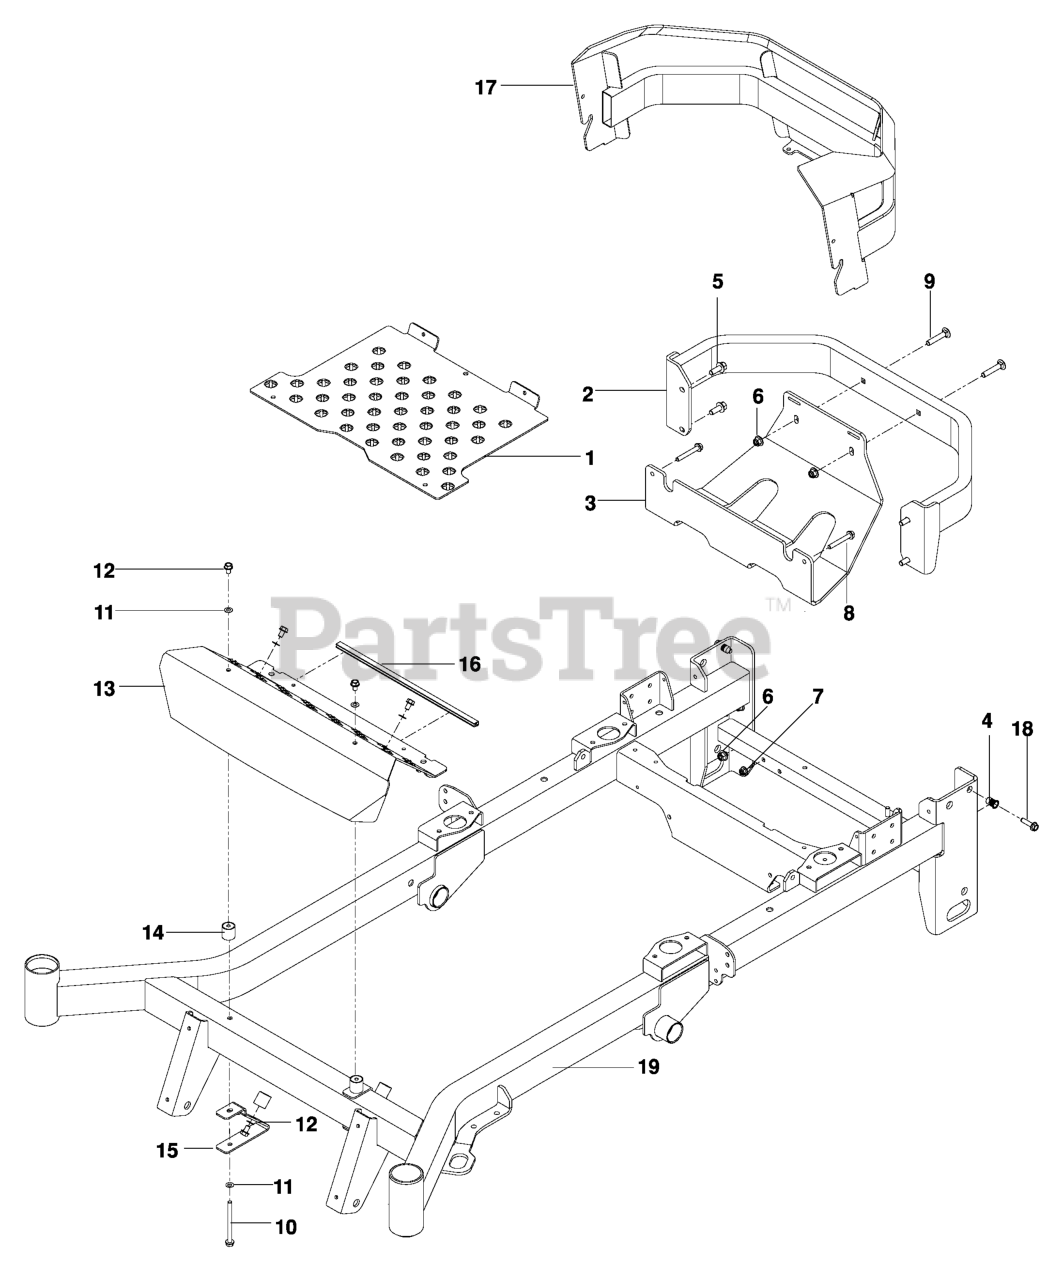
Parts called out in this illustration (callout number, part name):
1	PLATE, FLOOR PAN, OR
2	BUMPER.REAR.ORANGE
3	PLATE, SKID GRAY
4	NUTSERT 5/16-18 THICK GRIP
5	HHFS 3/8-16 X 1 GRD 5 ZD
6	NUT 3/8-16 HEX FLG NYLOC ZD
7	5/16-18 NYLOC FLANGE NUT
8	HHFS 5/16-18 X 2.25 GD 5
9	RHSNB 3/8C X 2
10	HHFS 5/16-18 X 3 3/4
11	WASH 5/16 DISC SPRING ZD
12	SCR 5/16-18 X 1/2 SELFTAP ZN
13	PLATE, FOOT REST, OR
14	MOUNT, F/F INSERT
15	BRACKET, REST MOUNT
16	RP.FLEX TRIM, BLK-LENGTH 1 FT
17	GUARD, REAR, GRAY
18	HHFS 5/16-18 X 1.25 TPBLT GD 5
19	FRAME W/DECALS, PZ
20	FRAME W/DECALS PZ 72
